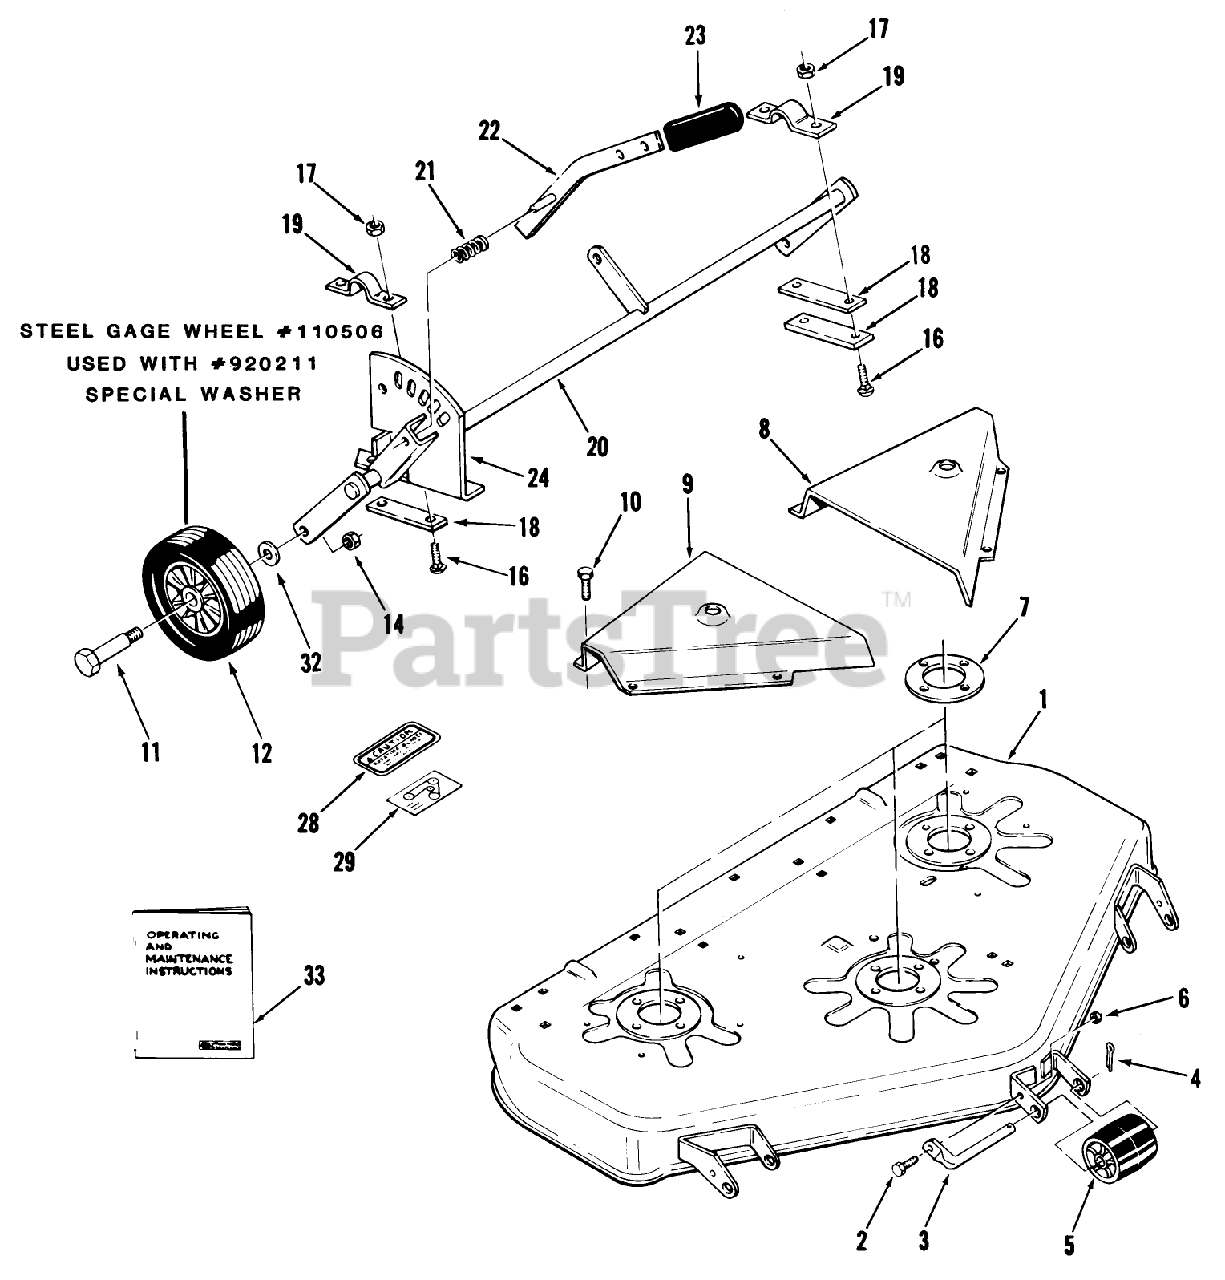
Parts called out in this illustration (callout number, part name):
7	PLATE-SPINDLE
10	Bolt
11	BOLT-SHOULDER
21	SPRING-COMPRESSION
29	DECAL-HEIGHT & BELT
32	WASHER-FLAT
33	Operating and Maintenance Instructions
